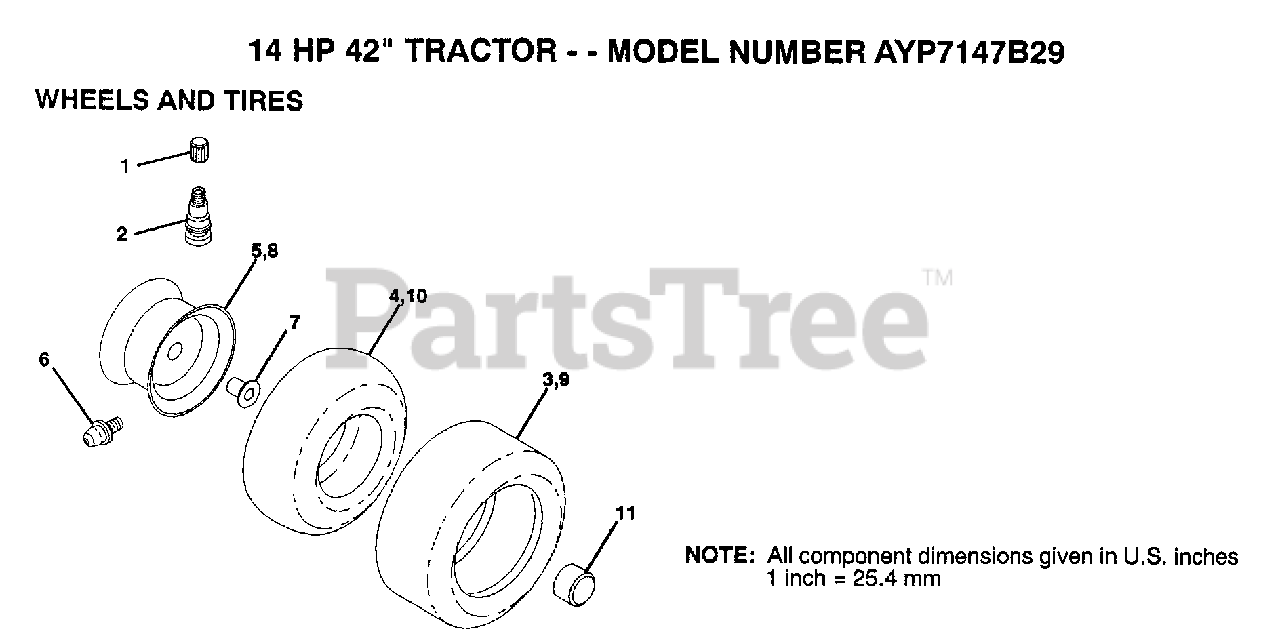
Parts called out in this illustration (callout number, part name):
1	VALVE CAP
2	VALVE STEM LT
4	TUBE.5.3/4.5/6
6	FITTING LT
7	"FLANGE, BEARING"
10	TUBE.18X9.5-8
11	HUB CAP
